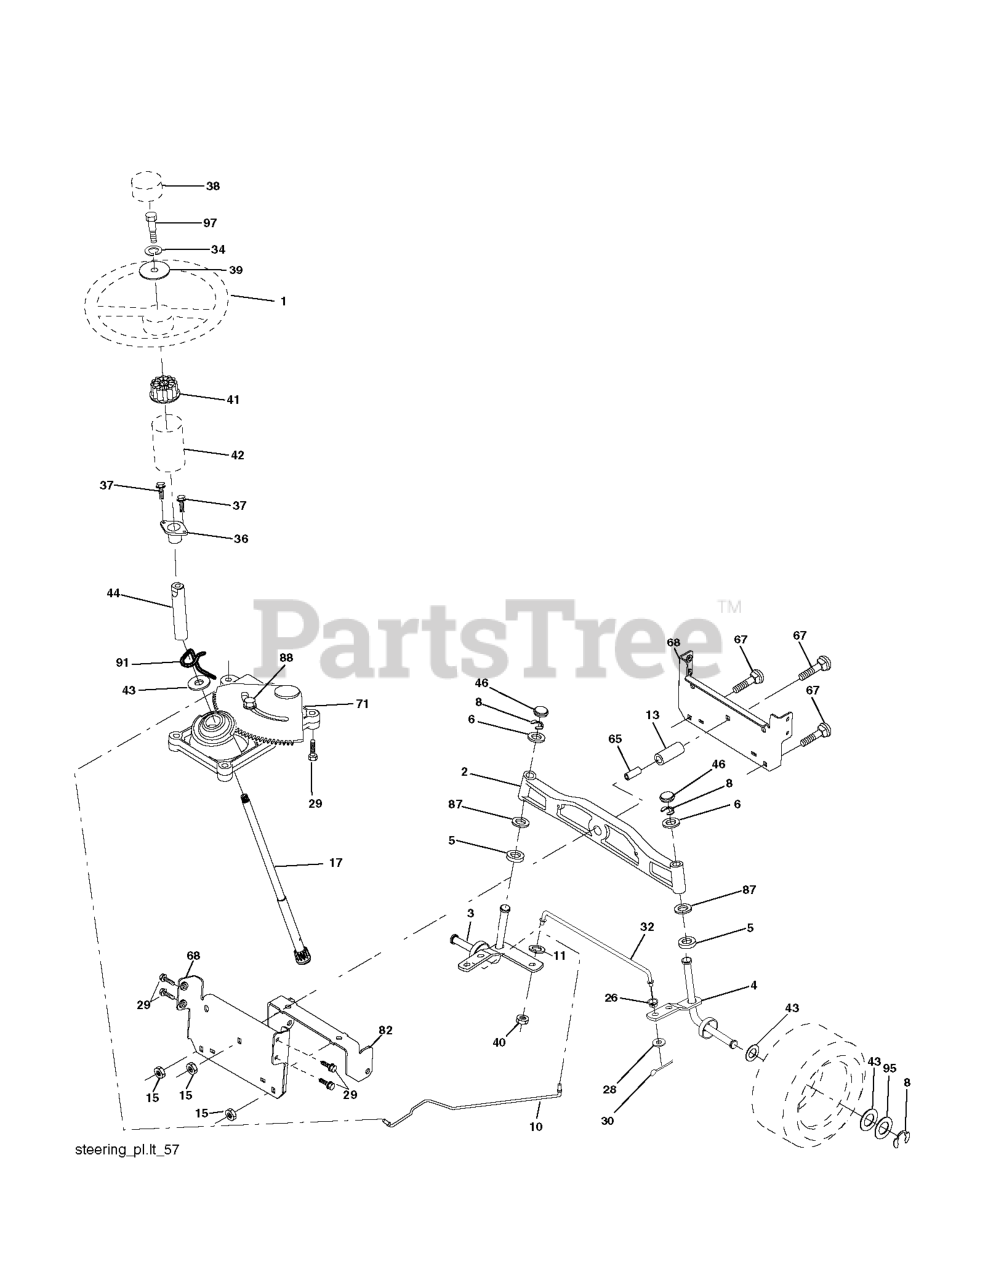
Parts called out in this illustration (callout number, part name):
1	STEERING WHEEL
2	AXLE ASSY FRONT
3	SPINDLE.ASM.LH.15"TIRES
4	SPINDLE.ASM.RH.15"TIRES
5	THRUST WASHER
10	DRAGLINK.15".TIRES.2001
11	WASHER, LOCK 3/8
13	TUBE, PIVOT AXLE
15	NUT
17	SHAFT STEERING SPLINE
29	SCREW, 3/8-16X3/4
33	WASHER M
34	WASHER.LOCK.HVY.HLCL.SPR.5/16
35	NUT, CROWNLOCK
36	BUSHING, STEERING
37	SCREW.TT.#10-32X.5.3/8.FLANGE
38	INSERT.CAP.STRG.WH.GRAY
39	WASHER.11/32
40	NUT CROWNLOCK 3/8-24
41	ADAPTER, WHEEL STNG..
42	BOOT, STEERING
44	SHAFT.EXTEN.STRG.SPLINE
46	CAP.SPINDLE.BLACK
65	SPACER BRACE AXLE
67	BOLT CARRIAGE
68	BRACE.AXLE.15"TIRES
71	STEERING ASM
82	BRACKET.SUSP.CHASSIS.FRONT.15
87	WASHER, FLAT .781 X 1 1/2"
88	BOLT, SHOULDER 7/16-20
91	CLIP.STEERING
95	WASHER.HARDENED
